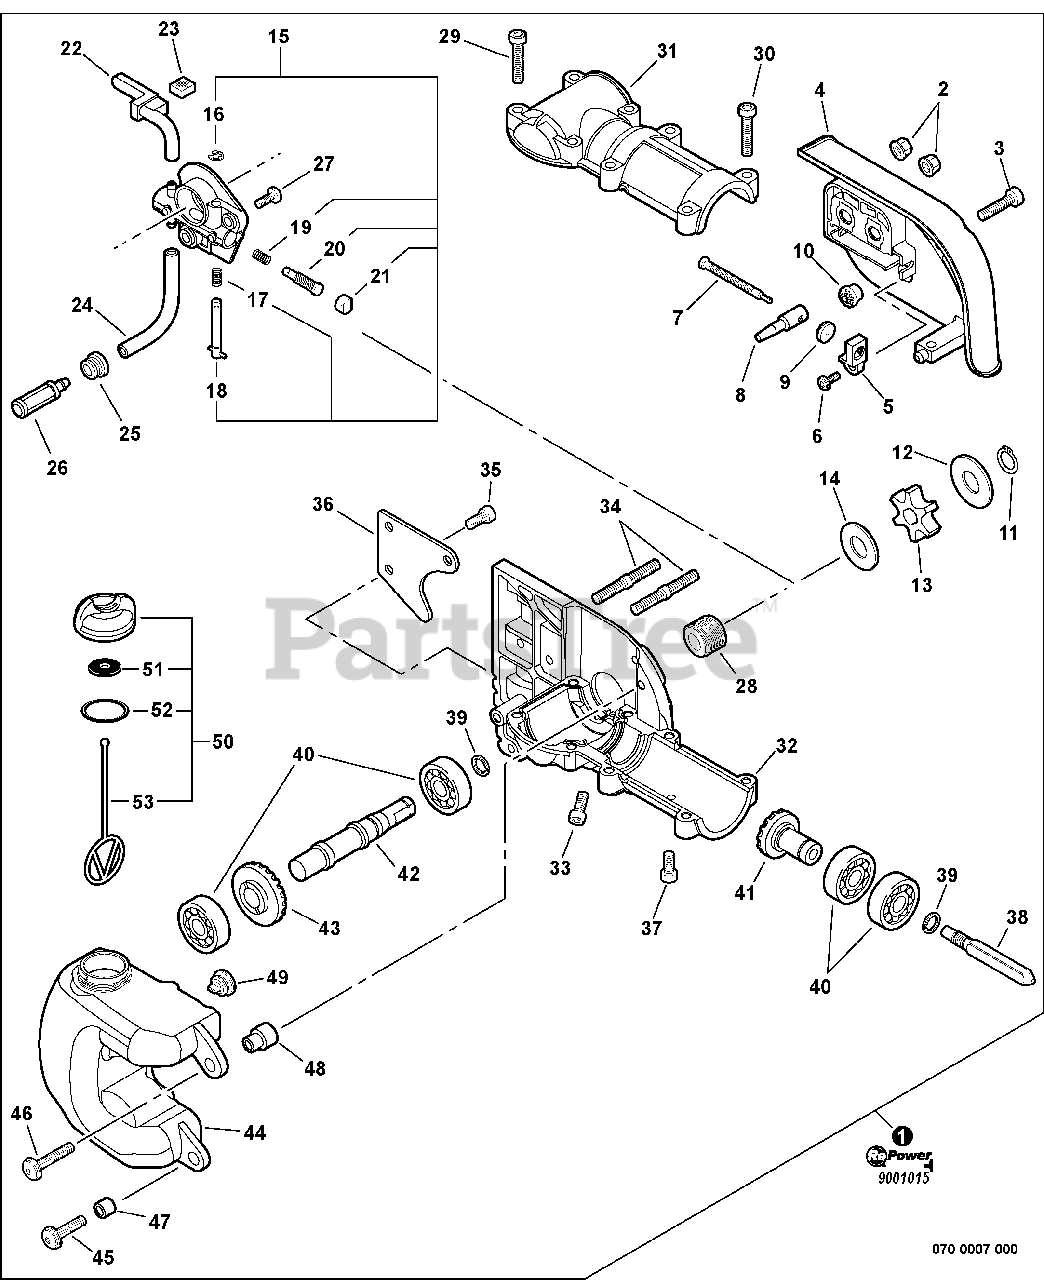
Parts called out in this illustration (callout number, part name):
1	GEAR CASE ASSY
2	NUT, FLANGE M6
3	SCREW M5×20
4	GUARD, SPROCKET
5	COLLAR 8
6	SCREW 4
8	TENSIONER, CHAIN
9	GEAR - 14 TOOTH
10	GEAR - 14 TOOTH
11	RING, SNAP
12	WASHER 10
13	SPROCKET, DRIVE
14	WASHER 10.2×24.5×1.2
15	AUTO-OILER ASSY
18	ADJUSTER, OILER
20	PLUNGER ASSY
21	CAP, PLUNGER
22	PIPE, OIL OUTLET
23	PAD, FOAM
24	PIPE, IMPULSE 3×6×75
25	GROMMET
26	FILTER, OIL
27	SCREW 5×10
28	GEAR, WORM
29	SCREW M5×25
30	BOLT 5×25
31	CASE, GEAR - UPPER Ø35
32	CASE, GEAR
33	SCREW 5×10
34	BOLT, STUD 6
35	SCREW 5×10
37	BOLT M5×10
38	CONNECTOR, DRIVE SHAFT
39	RING, SNAP Ø12
40	BEARING, BALL
41	GEAR, BEVEL - 15 TOOTH
42	SHAFT, GEAR
43	GEAR, BEVEL - 23 TOOTH
44	TANK, OIL
45	BOLT 5×20
46	SCREW M5×25
47	SPACER 6.2×7.8×6
48	COLLAR 6
49	VENT ASSY
50	CAP ASSY
51	GASKET, CAP
52	O-RING 18
53	CONNECTOR, CAP L= 60 MM
